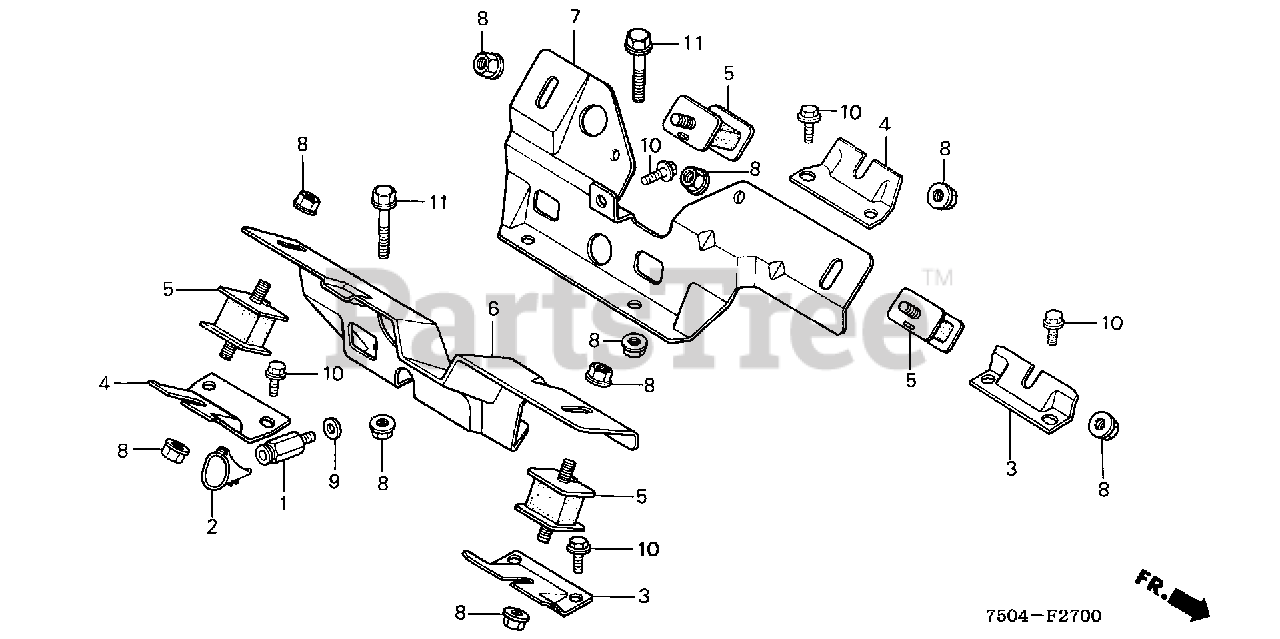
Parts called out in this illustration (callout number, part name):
1	JOINT, DRAIN
2	GUIDE, OIL DRAIN
3	STAY, FR. ENGINE MOUNTING
4	STAY, RR. ENGINE MOUNTING (NOT AVAILABLE)
5	RUBBER, ENGINE SETTING
6	STAY, R. ENGINE MOUNTING
7	STAY, L. ENGINE MOUNTING
8	NUT, FLANGE (10MM)
9	WASHER, DRAIN PLUG (12MM)
10	BOLT, FLANGE (8X14)
11	BOLT, FLANGE (10X40)
